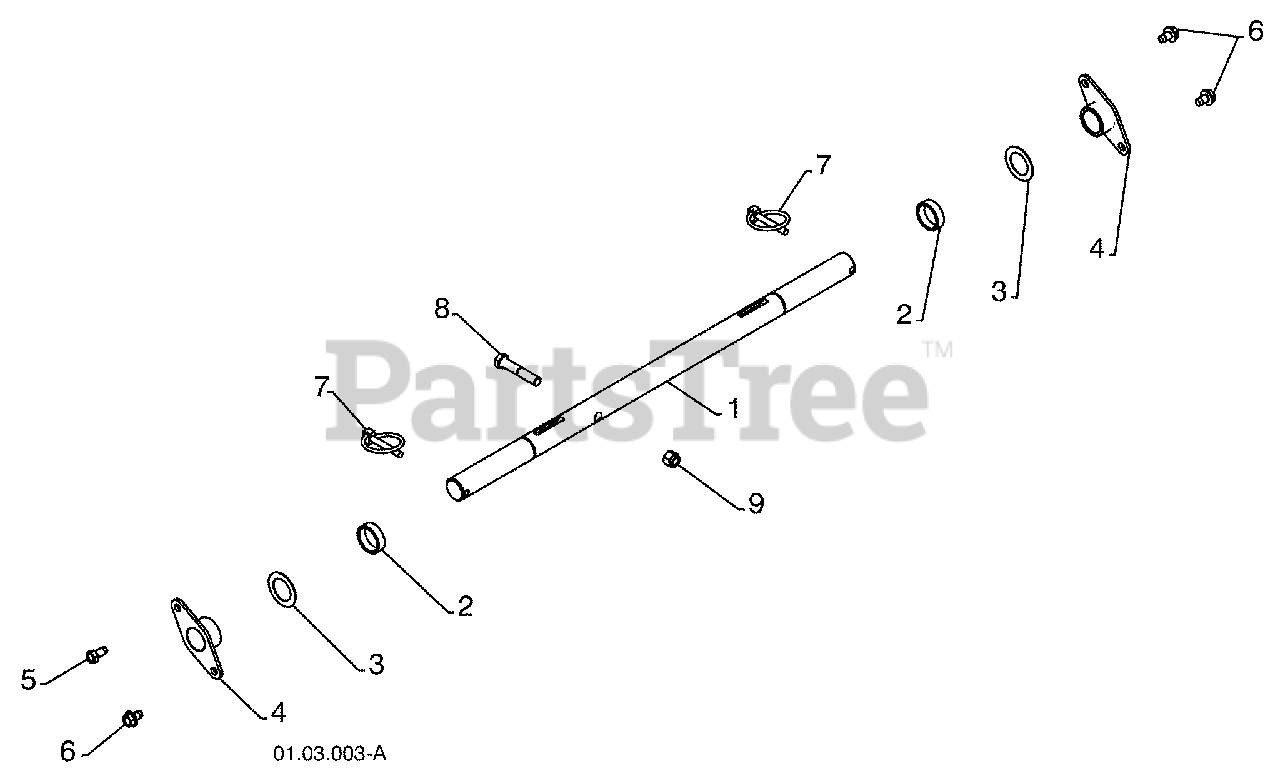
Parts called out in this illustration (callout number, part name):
1	AXLE SHAFT
3	THRUST WASHER
5	SCREW 5/16-18 X .625
6	BOLT 5/16-18 X .500
8	SCREW 3/8-16 X 2.00
9	NUT 3/8-16
